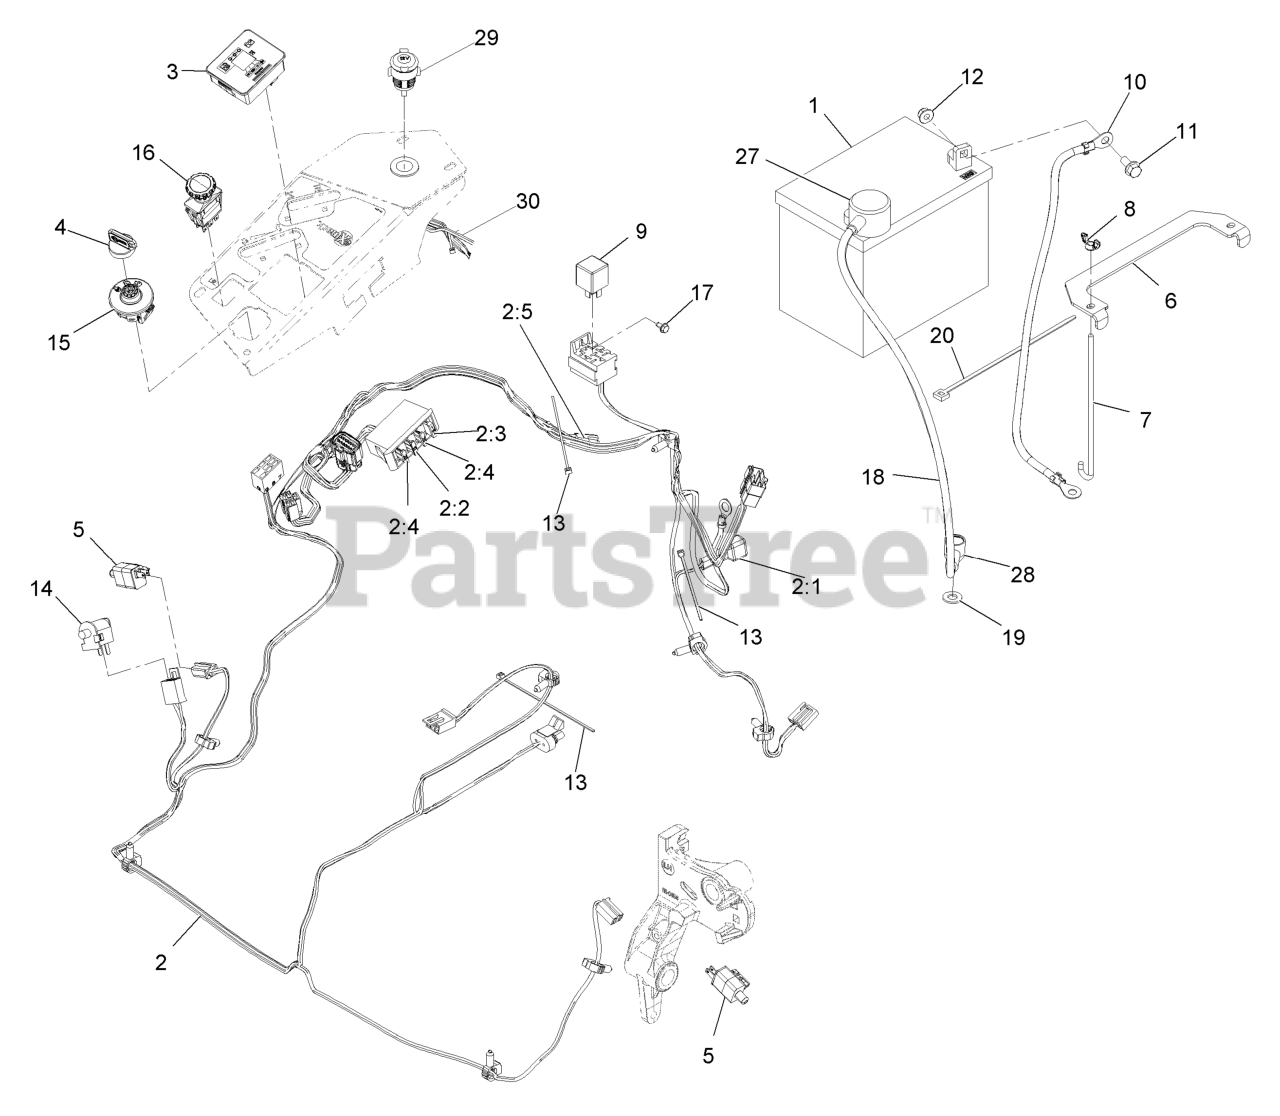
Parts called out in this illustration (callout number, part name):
1	Battery (300 Cca, Wet)
2	HARNESS-WIRE, MAIN
2:2	FUSE-BLADE, 10 AMP
2:3	FUSE-BLADE, 15 AMP
2:4	FUSE-BLADE, 25 AMP
2:5	CAP-PLUG
3	FUEL/HOUR METER ASM
4	KEY-IGNITION
6	STRAP-TIE DOWN, BATTERY
7	BOLT-HOLDDOWN
8	WINGNUT
10	CABLE-BATTERY, NEGATIVE
11	SCREW-HHF
12	NUT-HF, NI
13	TIE-CABLE
14	SWITCH-BAIL
16	SWITCH-PTO, 10 AMP
17	SCREW-HWH
18	CABLE-BATTERY, POSITIVE
19	WASHER-FLAT
20	TIE-PLASTIC
27	INSULATOR-BATTERY
28	INSULATOR-SOLENOID
29	RECEPTACLE-12V
30	HARNESS, RECEPTACLE 12V
